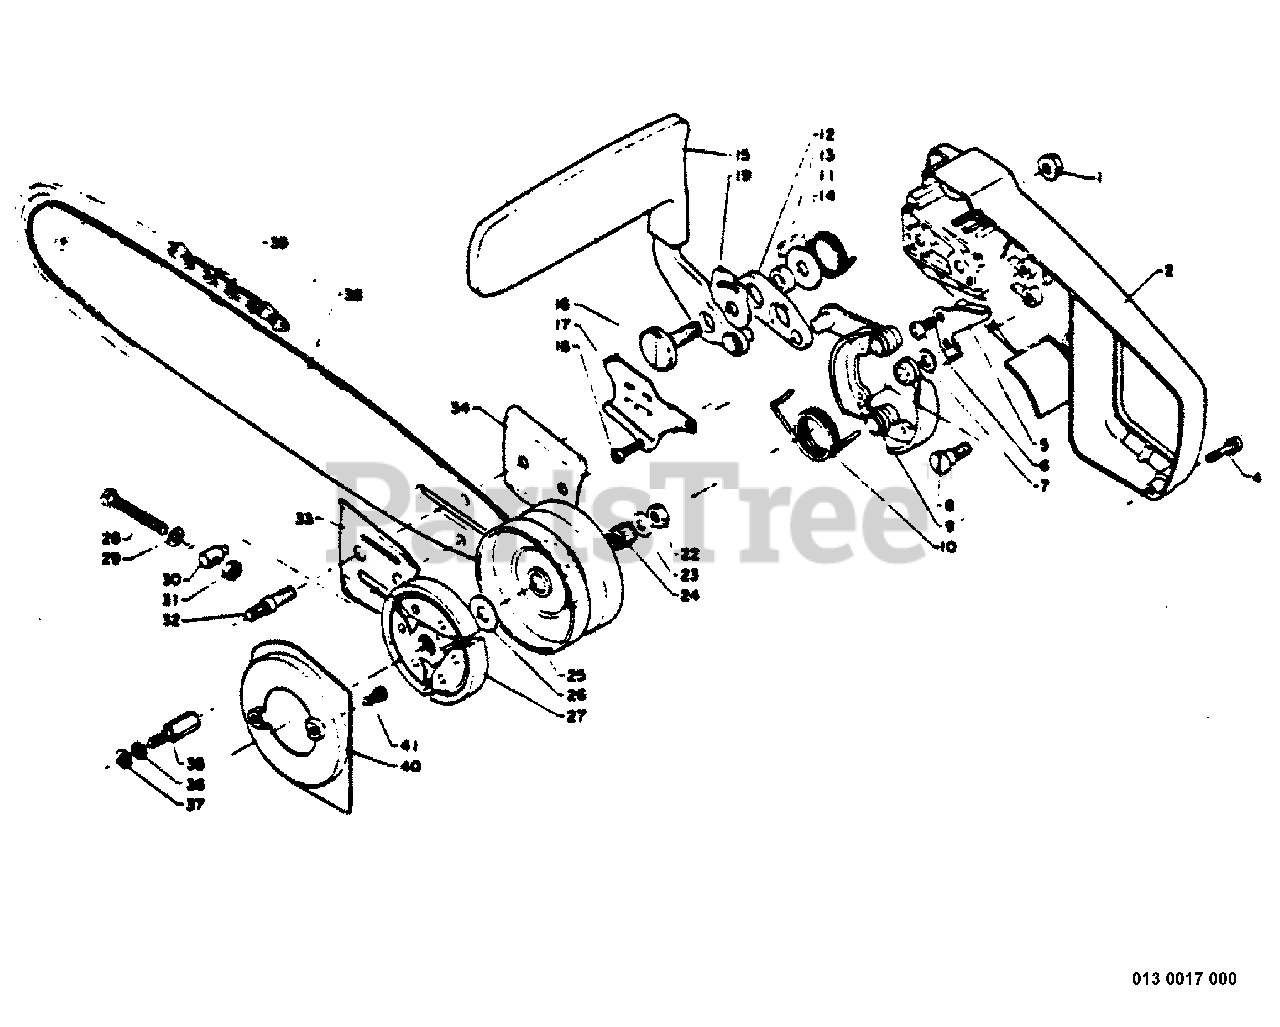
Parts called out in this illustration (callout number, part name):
1	NUT - 6 -- FLANGE
2	COVER, GUIDE BAR
4	SCREW
5	GUIDE, BRAKE SHOE
6	SCREW 5×8
7	WASHER 6.5×11.5×0.8
9	SHOE, BRAKE
10	SPRING
11	SPACER
12	CONNECTOR
13	SPACER, BRAKE HANDLE
14	SPRING, RETURN
15	HANDLE, BRAKE
17	SEAL, DUST
18	SCREW 4×10
19	WASHER
22	LOCKNUT - 6
23	WASHER
24	BEARING, NEEDLE 8
25	DRUM, CLUTCH
26	WASHER, CLUTCH
27	CLUTCH ASSY
28	SCREW, ADJUSTER
29	WASHER
30	TENSIONER
31	LOCKNUT - 5
32	STUD, GUIDE BAR
33	PLATE, GUIDE - INNER
34	PLATE, GUIDE - OUTER
35	CATCHER, CHAIN
36	WASHER, SPRING 5
37	WASHER, FLAT 5.5×10×0.8
38	GUIDE BAR - 14" (35 CM)
38	GUIDE BAR - 35" (89 CM)
38	GUIDE BAR - 40" (101 CM)
39	SAWING CHAIN -- 25-76E
39	SAW CHAIN - 25AP76E
39	SAWING CHAIN - 25 AP-84E
40	SEAL, DUST
41	SCREW 4×8
